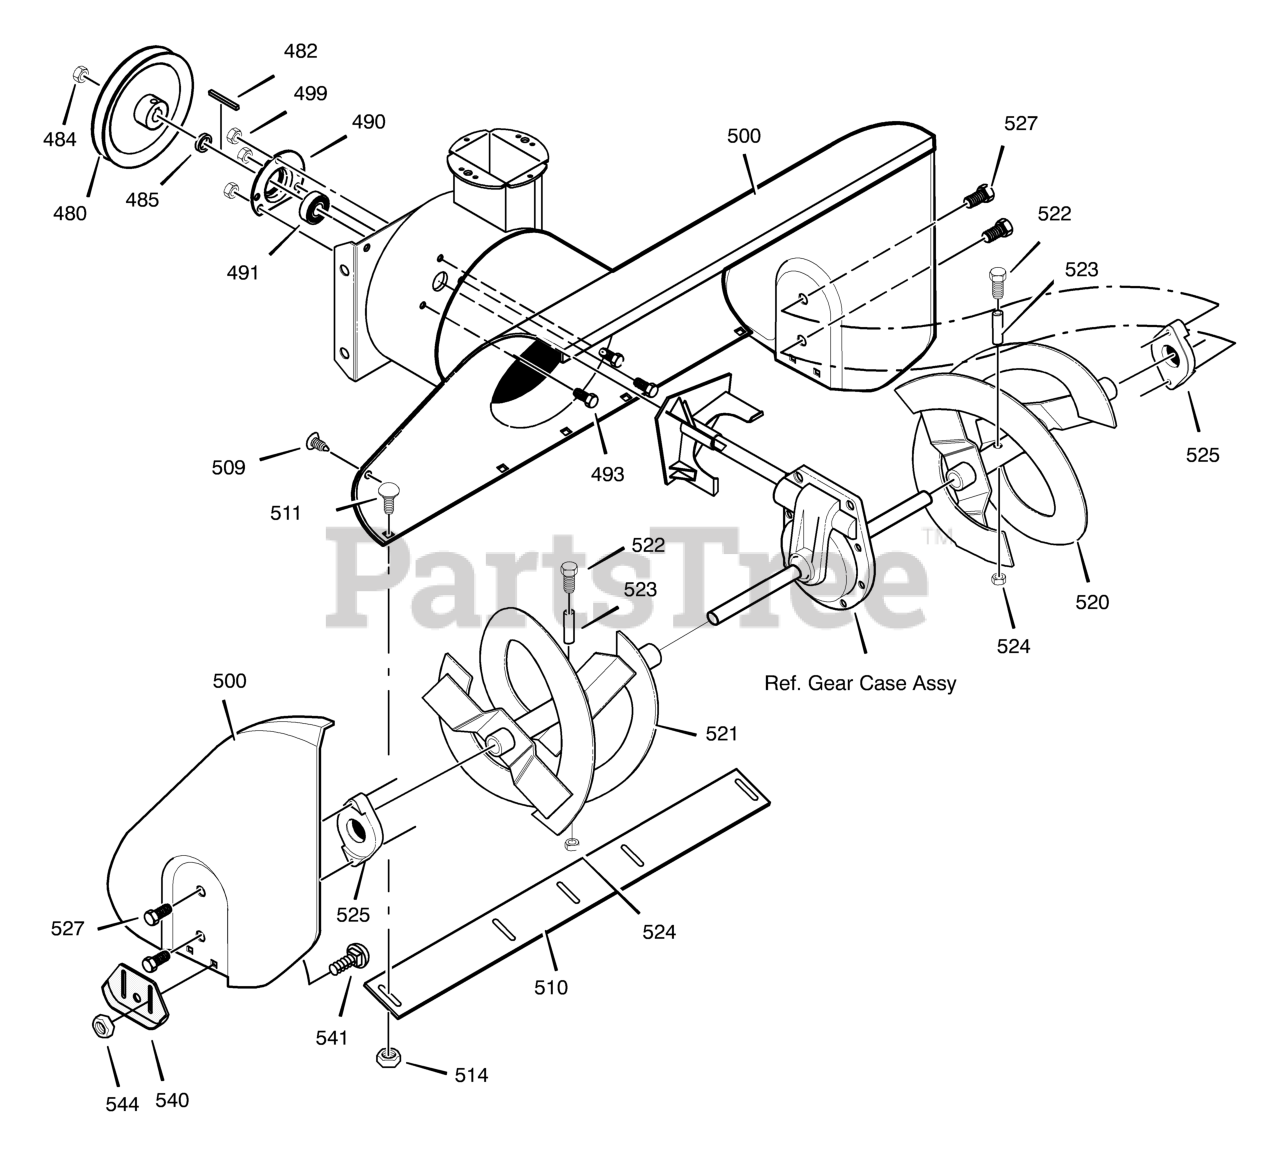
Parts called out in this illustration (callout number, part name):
480	PULLEY, 4L 8.40 OD
482	KEY, SQUARE 3/16 X 3/4
484	NUT, 1/2-20
485	SPACER, FRICTION PULLEY
490	RETAINER, BALL BRNG
491	BEARING, BALL
493	BOLT, HEX 5/16-18X .50
499	NUT, 5/16-18 HEXWDFLLK
500	HOUSING, ASSY
509	PLUG, CHRISTMAS TREE
510	BLADE, SCRAPER 29"
511	BOLT, 5/16-18X.75
514	NUT, 5/16-18
520	AUGER, ASSY, LH
521	AUGER, ASSY, RH
522	BOLT, 1/4-20 x 1.75
523	SPACER, SLEEVE
524	NUT, 1/4-20
525	BEARING,FLANGE
527	SCREW, 5/16-18 x 0.75
540	SKID, HEIGHT ADJUST
541	BOLT, 5/16-18 X .75
544	NUT, 5/16-18
